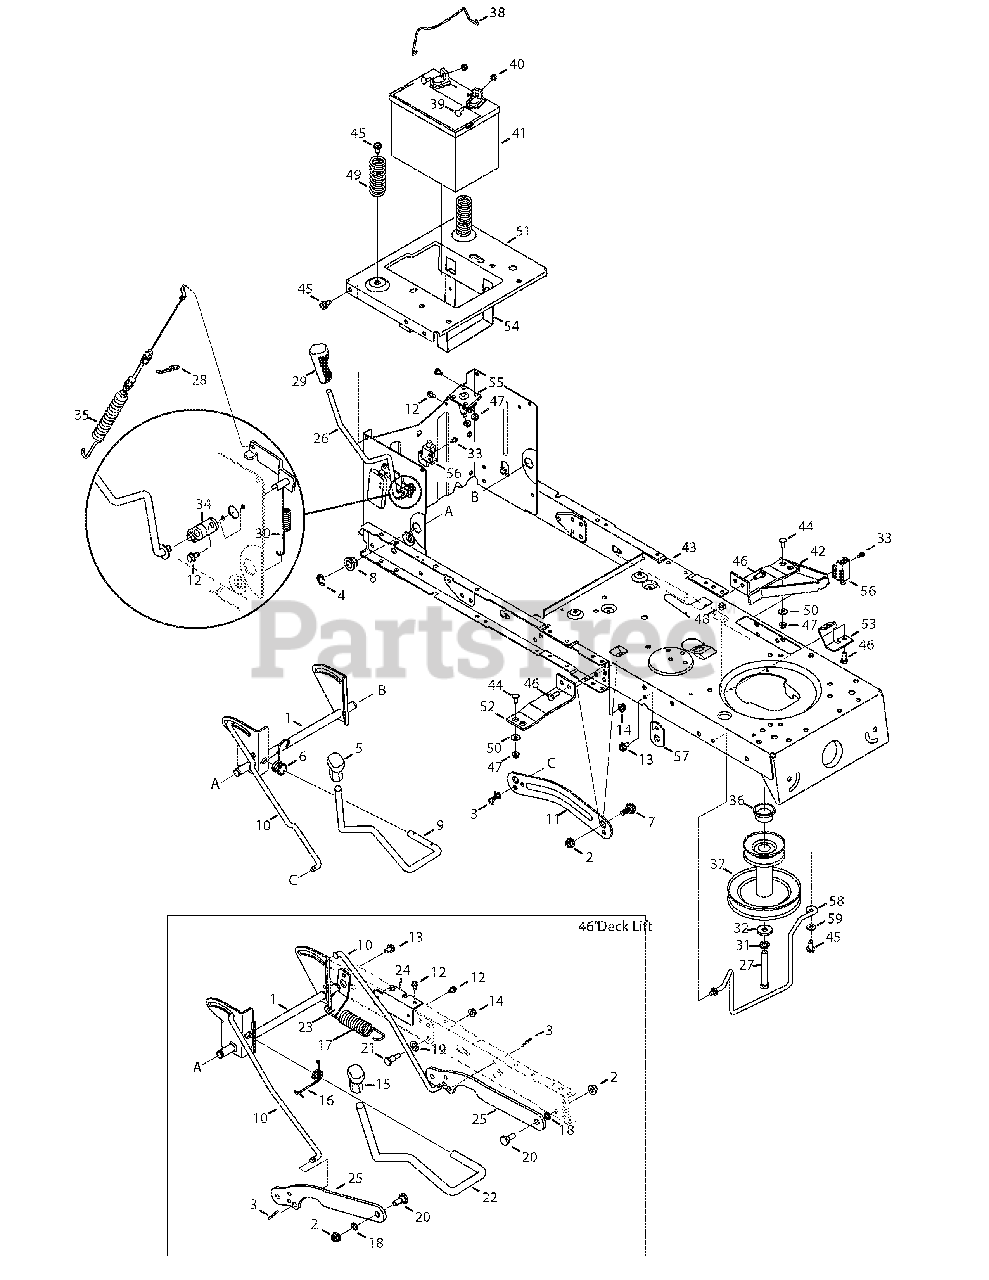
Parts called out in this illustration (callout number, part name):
2	Nut, Flange Lock, 3/8-16, GrF
3	Pin, Cotter .08 x 1.56 Intern. RH
4	Ring, E-Type, .625 Dia.
5	Grip, Handle, 1/2
6	Spring, Torsion 38/42" Decks
7	Screw, Shldr. , .625 x .175, 3/8-16
8	Bearing, Hex Flange
9	Deck Handle, Lift, 38/42" Decks
10	Rod, Lift
12	Screw, 1/4-20, 0.500
13	Screw, 5/16-18, 0.625
14	Flange Lock Nut, 5/16-18
15	Grip, Handle, 5/8
16	Spring, Torsion 46" Deck
17	Extension Spring
18	Washer, Flat, .385 x .62 x .063
19	Washer, Flat, .474 x .879 x .064
20	Bolt, Shldr. .500 x .270 3/8-16
21	Screw, Shldr. , .437 x .54
22	Deck Handle, Lift, 46" Deck
23	Lift Bracket
27	Screw, 7/16-20, 3.25 38 &42" Deck
28	Pin, Click, .092 x 1.64
29	Grip, Handle, 3/8
30	Spring, Extension
31	Washer, Lock, 7/16
32	Washer, Flat, .450 x 1.250 x .164
33	Shoulder Screw, #10-16, 0.500
34	Bearing, PTO
35	Cable, Deck Engagement
36	Spacer, 1.010 x 1.400 x .825
37	Engine Pulley, 38" & 42" Deck
39	Screw, Carriage, 1/4-20, .75, Gr5
40	Nut, Sems, 1/4-20
41	Battery, 190 CCA
44	Carriage Screw, 1/4-20 x .62
45	Screw, 5/16-18, .750
46	Hex Screw, 5/16-18 x .75
47	Nut, Flange Lock, 1/4-20, GrF
48	Hex Lock Nut, 5/16-18
49	Spring, Compr. , 1.28 OD x 3.125
50	Flat Washer, .28 x .74 x .063
55	Solenoid
56	Switch, Interlock
59	Washer, Flat, .406 x .875 x .059
